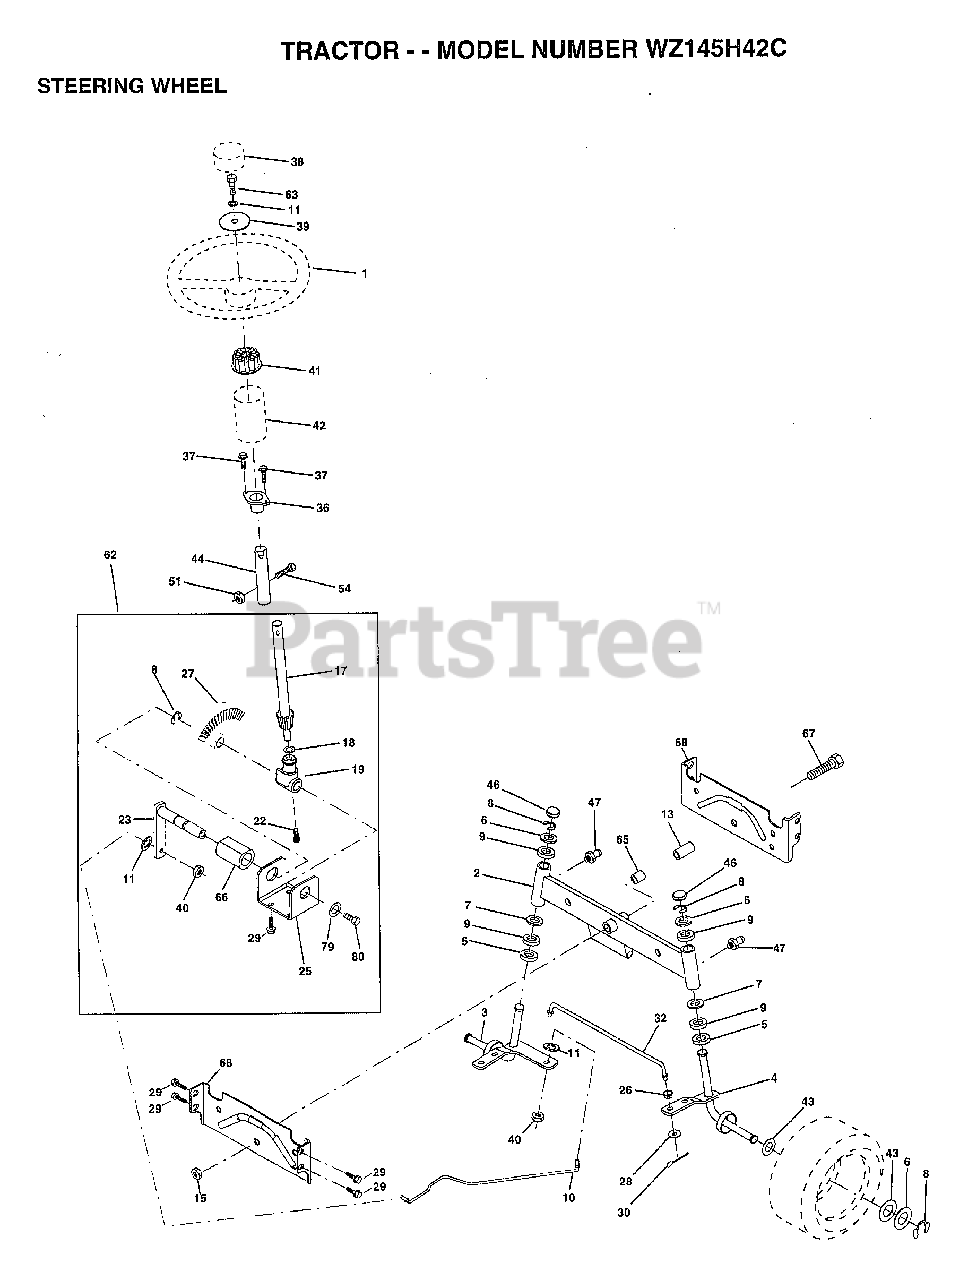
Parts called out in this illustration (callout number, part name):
1	WHEEL STR AYP BLK
2	AXLE ASM
3	SPINDLE.ASM.LH
4	"SPINDLE ASM,RH"
5	WASHER .T
6	WASHER
7	WASHER
8	RING
9	COL. SRTG. BEAR.
10	DRAGLINK-STAMPED
11	LOCKWASHER
13	BEARING AXLE
15	"NUT-LOC,FLANGE LT"
17	SHAFT ASM STEERIN
18	THRUST WASHER
19	SUPPORT.SHAFT.STEER
22	SCREW.HX.WSH.HD
23	SHAFT.ASM.PITMAN
25	BRKT-STEERING
26	BUSHING.DRAGLINK
27	GEAR SECTOR
28	WASHER
29	SCREW
30	COTTER PIN
32	TIE ROD
36	BUSHING.STEERING
37	"SCREW-TT,10-32 FL"
38	CAP STEER AYP
39	WASHER T
40	GRIPCO NUT
41	ADAPTER LT
42	BOOT.STEER.PL
43	WASHER
44	EXT SHAFT STEERIN
46	CAP
47	ZERK M
51	NUT
54	BOLT
62	KIT.STEER.ASM
63	BOLT
65	SPACER AXLE
66	"BEARING-ARM,PITMA"
67	BOLT
68	BRACE AXLE
79	WASHER
80	BOLT.HX.NYLON3/8-16X3/
